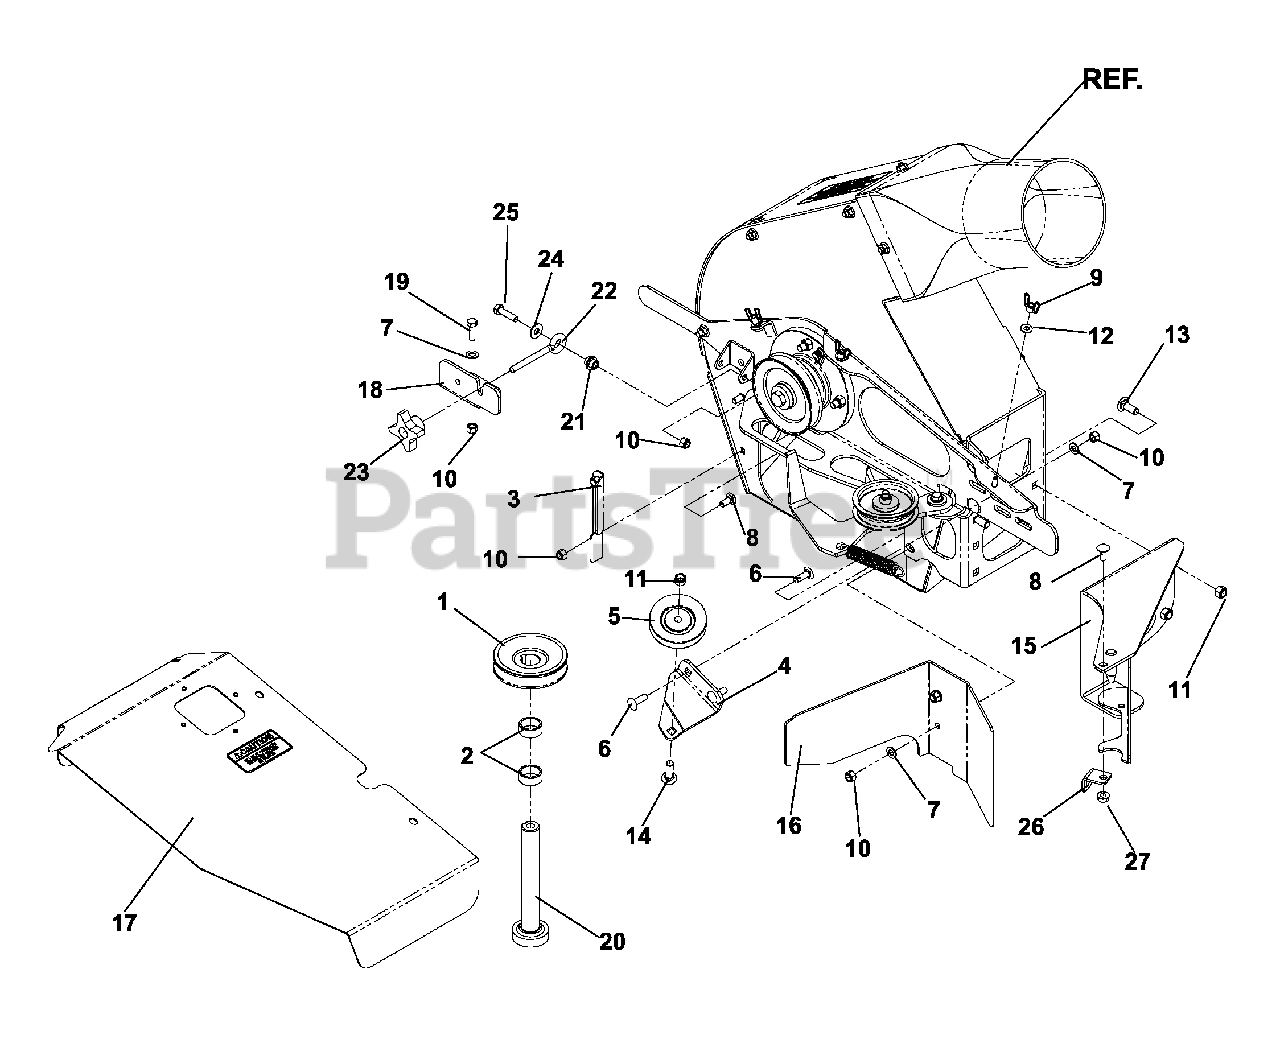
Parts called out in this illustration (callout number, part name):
1	V-PULLEY
2	HUB BEARING SPACER
4	FIXED IDLER BRKT.
5	PULLEY, IDLER 3 METAL
6	RHSSNB 5/16C X 1.0
7	FLAT WASHER 5/16 SAE
8	BOLT 5/16C X 3/4" CARRIAGE
9	WING NUT 1/4
10	NUT 5/16 NYLOC
11	NUT 3/8-16 NYLOC
12	1/4` SAE FLAT WASHER
13	RHSNB 3/8C X 1
14	RHSNB, 3/8-16 X 1-1/2
15	PIVOT WLDT.
16	BLOCK OFF PLT
17	GUARD ASSEMBLY, 60"
18	LATCH RECEIVER
19	HCS 5/16C X 1
20	SHAFT LONG
21	SPRING CAP
22	EYE BOLT 5/16 X 3.50
23	SEAT KNOB 5/16-18
24	WASHER 5/16 FLAT
25	HCS 5/16C X 1 1/4
26	SPRING BRKT.
27	5/16-18 FLANGED L-NUT
